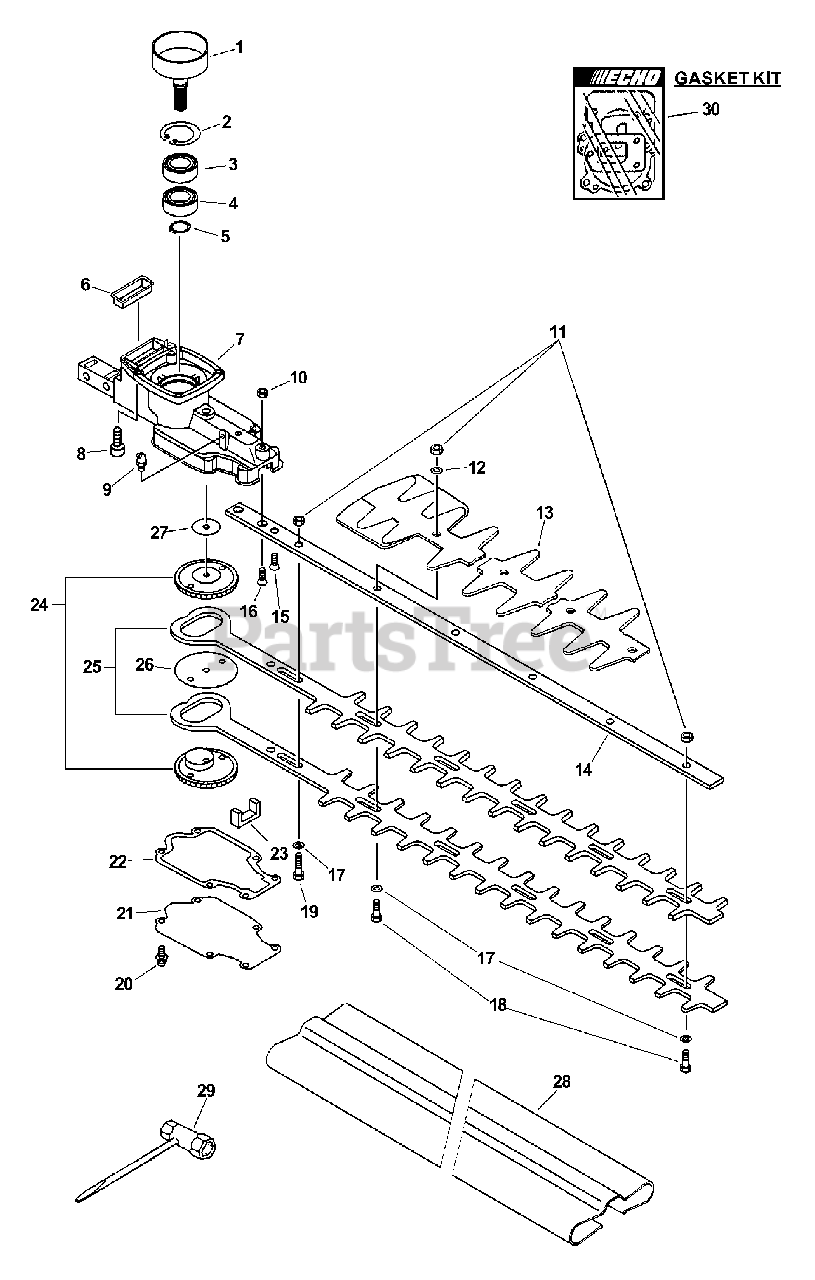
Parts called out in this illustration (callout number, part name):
1	DRUM, CLUTCH
2	RING, SNAP 35
3	BEARING, BALL 6202
4	BEARING, BALL 6202
5	RING, SNAP 14
6	CUSHION, FUEL TANK
7	CASE, GEAR
8	BOLT 4×16
9	FITTING, GREASE
10	NUT, HEX M6
12	WASHER 6.5×15.5×0.6
13	STIFFENER
14	SUPPORT, BLADE
15	SCREW 5×30
16	SCREW 6×30
17	WASHER 6.5×15.5×0.6
18	BOLT 6×18
19	BOLT M6×35
20	BOLT 4×12
21	LID, GEAR CASE
22	GASKET, GEAR CASE
24	GEAR, SPUR
25	BLADE, TRIMMER
26	WASHER 6.7×54×0.38
27	WASHER 6.5×30×0.2
28	COVER, BLADE
29	T-WRENCH 13×19×180
30	GASKET KIT
